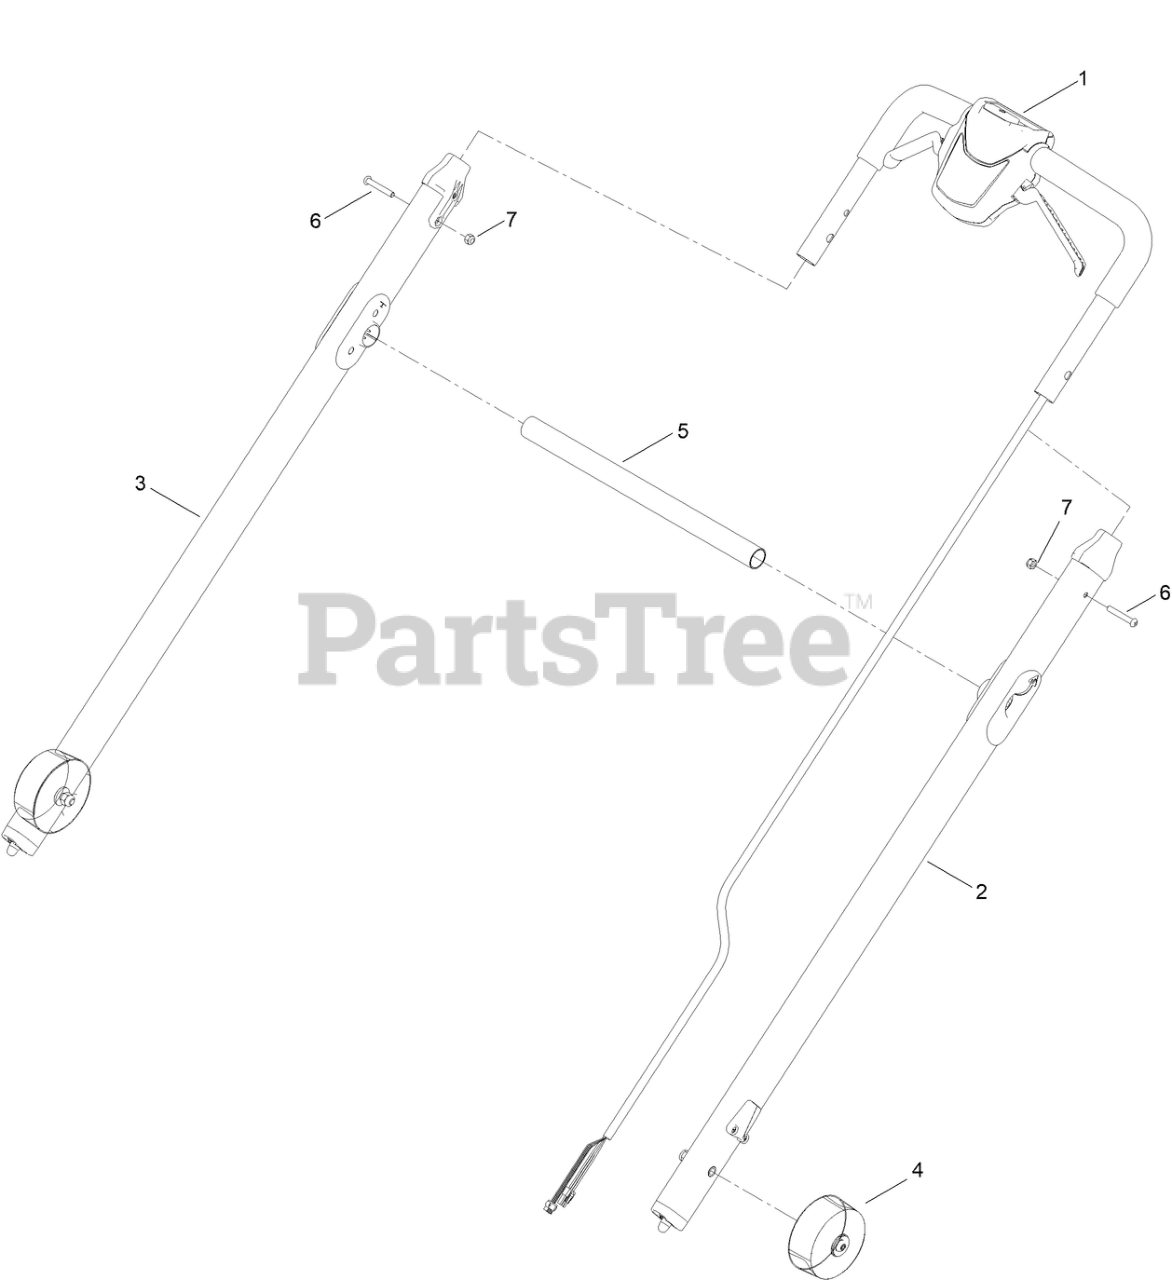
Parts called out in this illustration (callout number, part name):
1	CONTROL LEVER ASM, PUSH
2	HANDLEBAR ASM, LH
3	HANDLEBAR ASM, RH
4	HANDLEBAR END CAP
5	BRACE, HANDLEBAR RELEASE
6	BOLT, M6X40
7	NUT, NYLOC, M6X1
